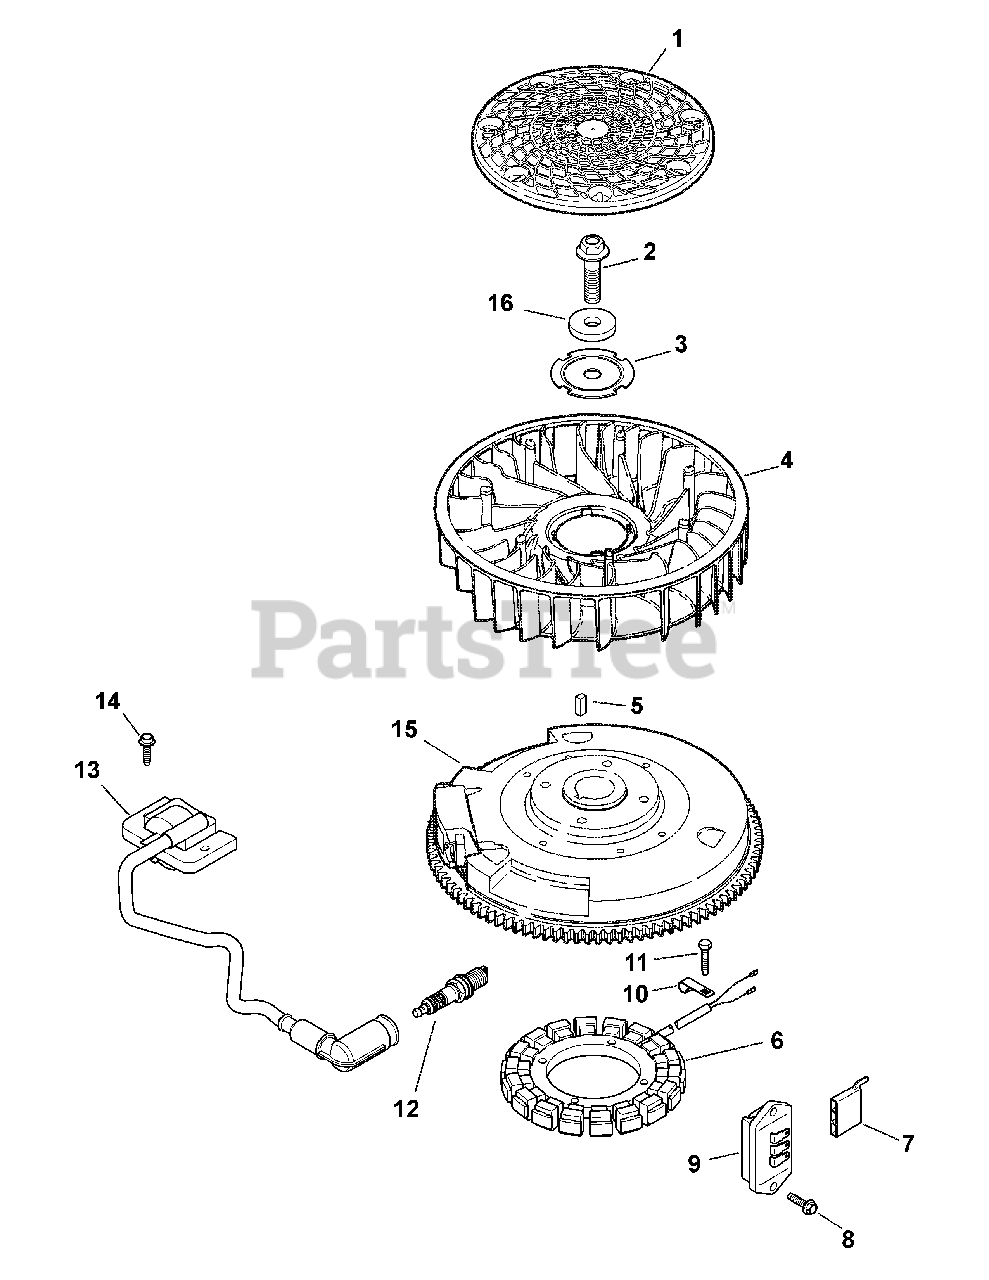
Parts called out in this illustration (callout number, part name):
1	Screen, Grass
2	Screw, Hex Flange
3	Plate, Fan Mounting
5	Key, Straight Flywheel
8	Screw, Flg Thd Frm M5X.8X20
9	Regulator/Rectifier
11	Screw, Thd Frm M5X0.8X25
12	Plug, Spark (Std)
13	Module, Ignition (Cdi Fixed)
14	Screw, Flg Thd Frm M5X.8X20
15	Flywheel
